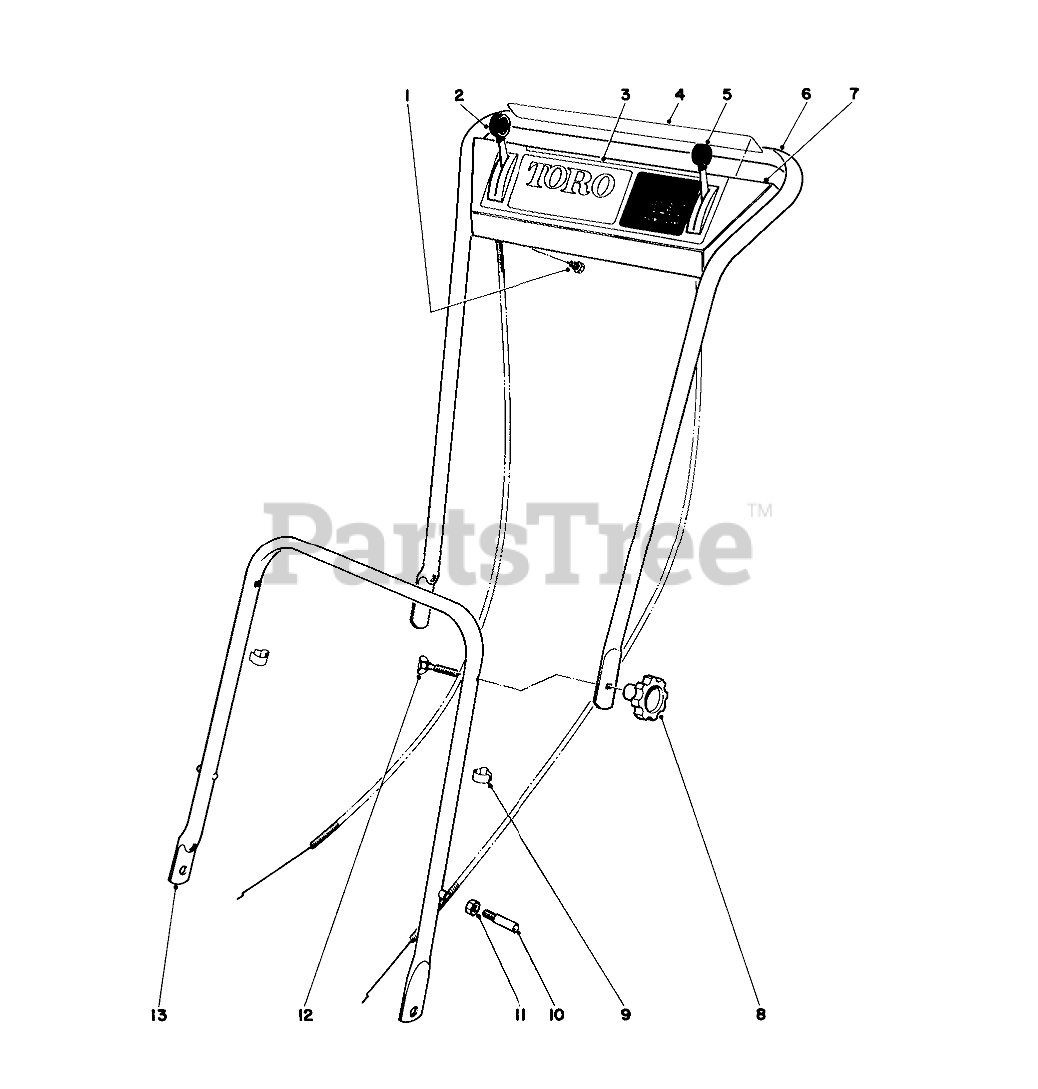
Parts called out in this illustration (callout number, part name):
1	SCREW-HWHTF
2	Throttle Control
3	Decal, Escutcheon Plate (Model 16273)
4	Decal, Safety
5	Traction Control (Model 16273 only)
6	UPPER HANDLE
7	Escutcheon Plate (Model 16273)
10	Handle Pin
11	Nut
12	SCREW-HANDLE
13	LOWER HDLE STKD ASM
